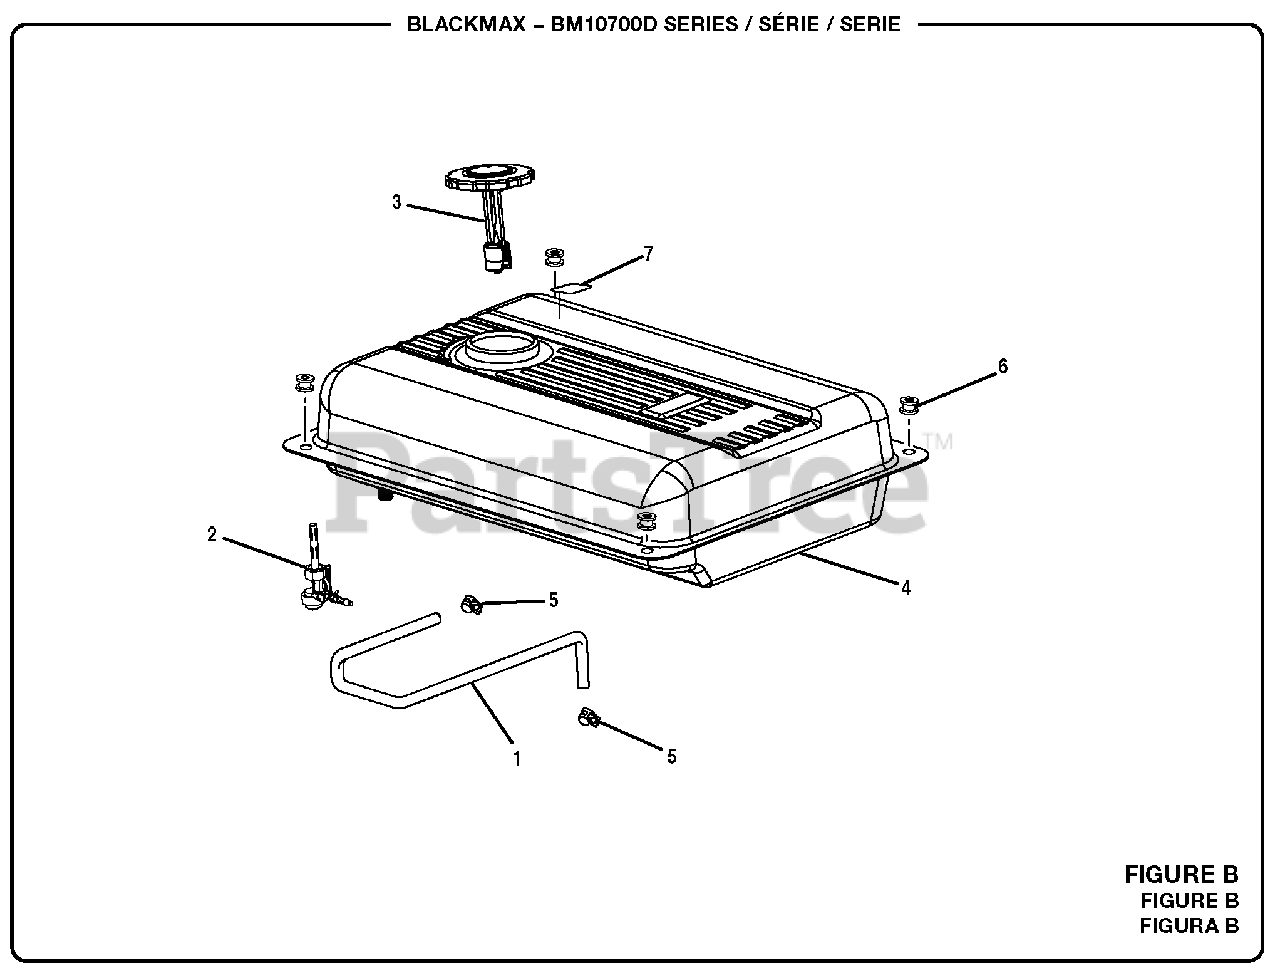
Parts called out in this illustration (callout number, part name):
1	Fuel Line Hose (1/4 ID x 17-1/4 in.)
2	Fuel Shut Off Valve w/Filter
3	Fuel Cap Assembly
4	Fuel Tank (8 Gal, Incl. Key No. 7)
5	Fuel Line Clamp (3/8 in.)
6	Bushing w/Insert
7	E85 Label
